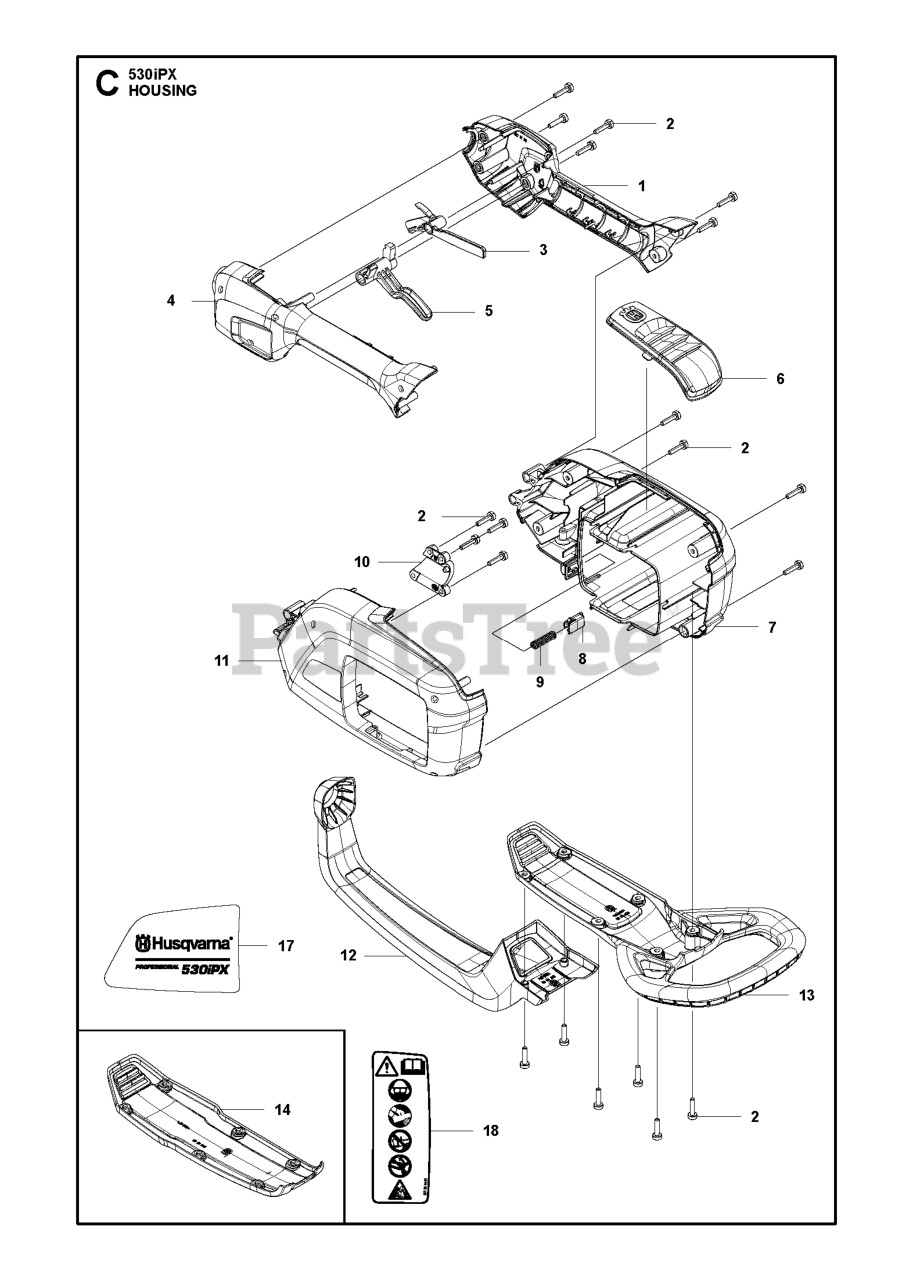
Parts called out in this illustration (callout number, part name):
1	FILTER AIRBOX
1	HANDLE HALF RIGHT
2	SCREW
3	RP_AIR BOX
3	THROTTLE LOCKOUT
4	CHOKE LEVER
4	HANDLE HALF LEFT
5	KIT GASKET CARB
6	CARB ADAPTOR
7	KIT GASKET 28CC TRIMMER
7	HOUSING RIGHT
8	BOLT CARB ADAPTOR
8	PUSH BUTTON
9	CYLINDER
9	SPRING PUSH OUT
10	Plug - Spark (RCJ-8Y)
11	KIT SEAL CRANKSHAFT
11	HOUSING LEFT
12	WASHER STARTER
12	TRIGGER GUARD
13	SPRING STARTER CUP
13	BUMPER SKID PLATE
14	ASSY-STARTER CUP
14	SKID PLATE
15	COUPLING STARTER
16	FUEL PICK-UP ASSY
17	KIT FUEL LINE
18	ASSY-CAP W/RETAINER
19	O RING NITRILE
20	ASSY FUEL TANK
21	REAR SHROUD
24	STARTER HANDLE GRAY
25	SCREW M5-0.8X30MM
26	STARTER HOUSING
27	%KIT STARTER SPRING
28	KIT STARTER PULLEY
30	ASSY-STARTER HSG.
31	ISOLATOR FUEL TANK
32	BOLT MUFFLER
33	SCREW-10-16 X 1/2 HI-LO
34	SHIELD HEAT
35	SCREW M4 X 1.75 PT 16MM
36	MUFFLER GUARD
37	KIT SPARK ARRESTOR SCREEN
38	ASSY MUFFLER NC
39	GASKET PAPER METAL
40	SCREW-M5-0.8 X 25MM(TAP)
41	IGNITION MODULE MBU-7
42	ASSY MODULE LEAD WIRE
43	SCREW M4 X .70 TT 16MM
45	WASHER-CLUTCH
48	NUT HEX LOCK 10-24
49	SCREW M4 X .70 TT 16MM
50	FAN HSG ASSY
51	ASSY-CLUTCH DRUM
52	%KIT CLUTCH ASSY
53	SPACER FLYWHEEL
55	CRANKCASE CASTING
56	BEARING RADIAL BALL (6201)
57	KIT CRANKSHAFT ASSY
58	WRIST PIN RET.
59	RING PISTON
60	KIT PISTON 28CC TRIMMER
61	KIT GASKET 28CC TRIMMER
62	SCREW-M5-0.8 X 25MM(TAP)
63	CARBURETOR KIT
64	COVER-AIR BOX
65	KNOB ASSY AIRBOX COVER
66	KIT GASKET 28CC TRIMMER
